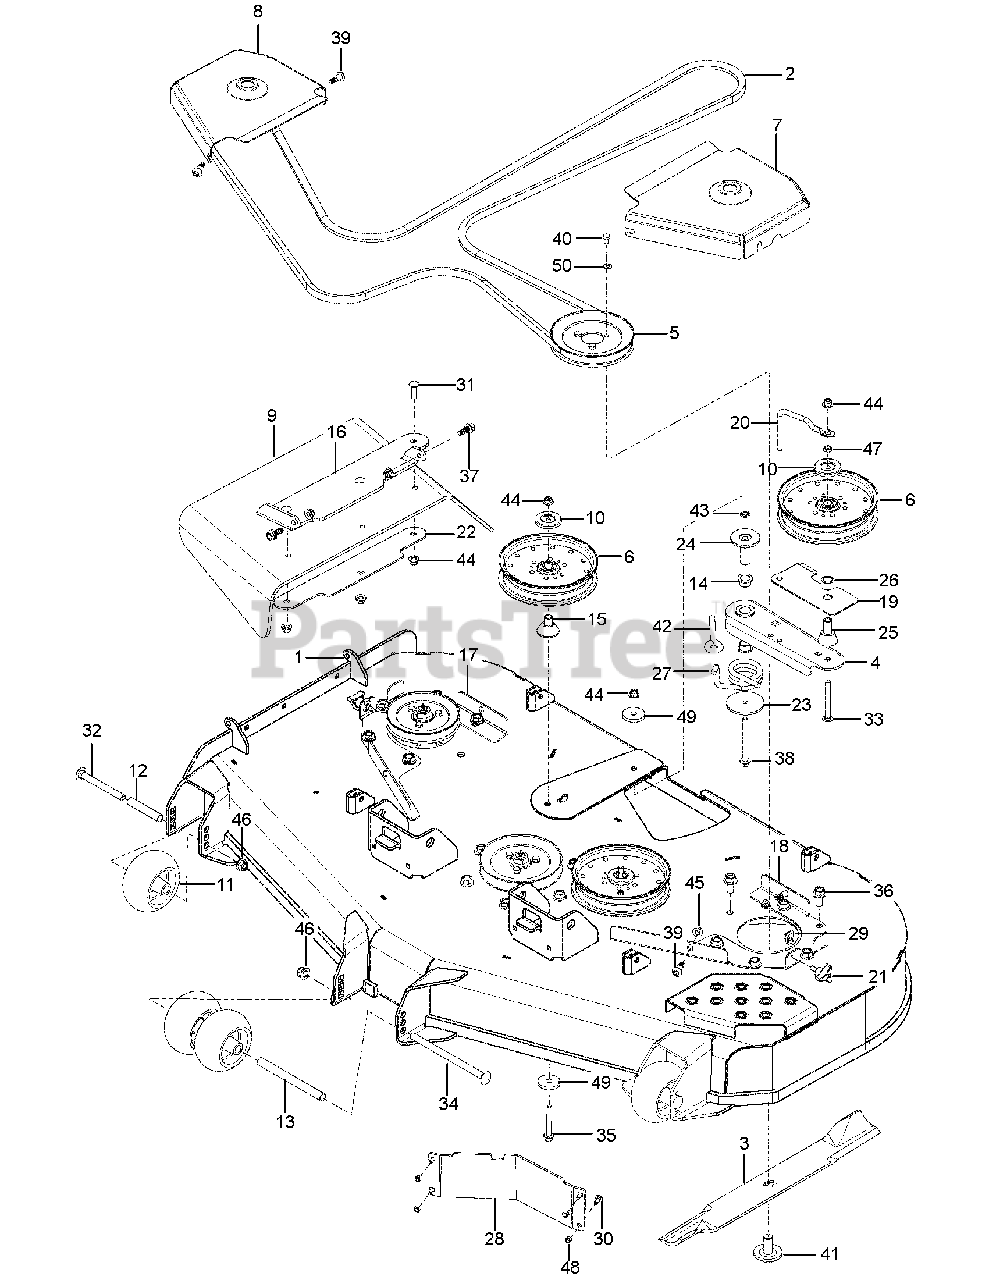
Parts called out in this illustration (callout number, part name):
1	DECK.W/DECALS.60".7GA.ORG
2	BELT 5V 176.00
3	BLADE - HEAVY DUTY 21"
4	ARM.PNT.WLD.TENSIONR.IDLER.BLK
5	PULLEY - 6.57
6	PULLEY - IDLER 7"
7	COVER.PULLEY.LH.PNT
8	COVER.PULLEY.RH.PNT
9	Discharge Chute
10	DUST SHIELD
11	ROLLER, GAUGE .635 BORN
12	TUBE, ROLLER AXLE
13	TUBE, ROLLER AXLE LONG
14	BEARING, FLANGE
15	BEARING, IDLER ARM
16	BRACKET.CHUTE.ORG
17	BRACKET PULLEY COVER MOUNT LH
18	BRACKET PULLEY COVER MOUNT RH
19	BELT.GUIDE.LOWER.PLATE.MS431
20	KEEPER KEEPER., BELT
21	KNOB W/STUD
22	PLATE.BACKING.DISCHARGE.CHT.BK
23	PLATE.SPRING.RETAINER
24	SHAFT.MOUNT.ARM.IDLER
25	Idler Spacer
26	Pulley Intermediate Spacer
27	SPRING.TORSION.DECK.IDLER.TMSN
28	BAFFLE, DIVERTER 54"/60" LH
29	U-CLIP 5/16-18 NUT RETAINER
30	1/4-20X3/4 CARR BLT
31	BOLT.3/8-14X1.25
32	RHSNB 1/2-13 X 4.75 GR5 ZD
33	BOLT.RDHD SQNK 3/8-16 X 3-1/2
34	RHSNB 1/2-13 X 8 GR5 ZD
35	HHFS 3/8-16 X 2-3/4 GR5 ZD
36	HHFS 1/2-13 X 1 GR5 ZD
37	HHFS 3/8-16 X 1 GRD 5 ZD
38	HHFS 3/8-16 X 4 GR5 ZD
39	SCREW.SHLDR.3/8 X 1/2.5/16-18
40	HCS 5/16-18 X 1/2 GR 5 ZD
41	BLADE BOLT/WASHER
42	EYE BOLT, 3/8 X 4"
43	NUT 3/8 PALNUT RTNG BLK PHOS
44	NUT 3/8-16 HEX FLG NYLOC ZD
45	5/16-18 NYLOC FLANGE NUT
46	NUT, 1/2-13 HEX FLG NYLOC ZD
47	NUT 3/8-16 HEX JAM
48	RP_NUT 1/4-20 NYLOC
49	SPINDLE WASHER
50	WASH 5/16 DISC SPRING ZD
